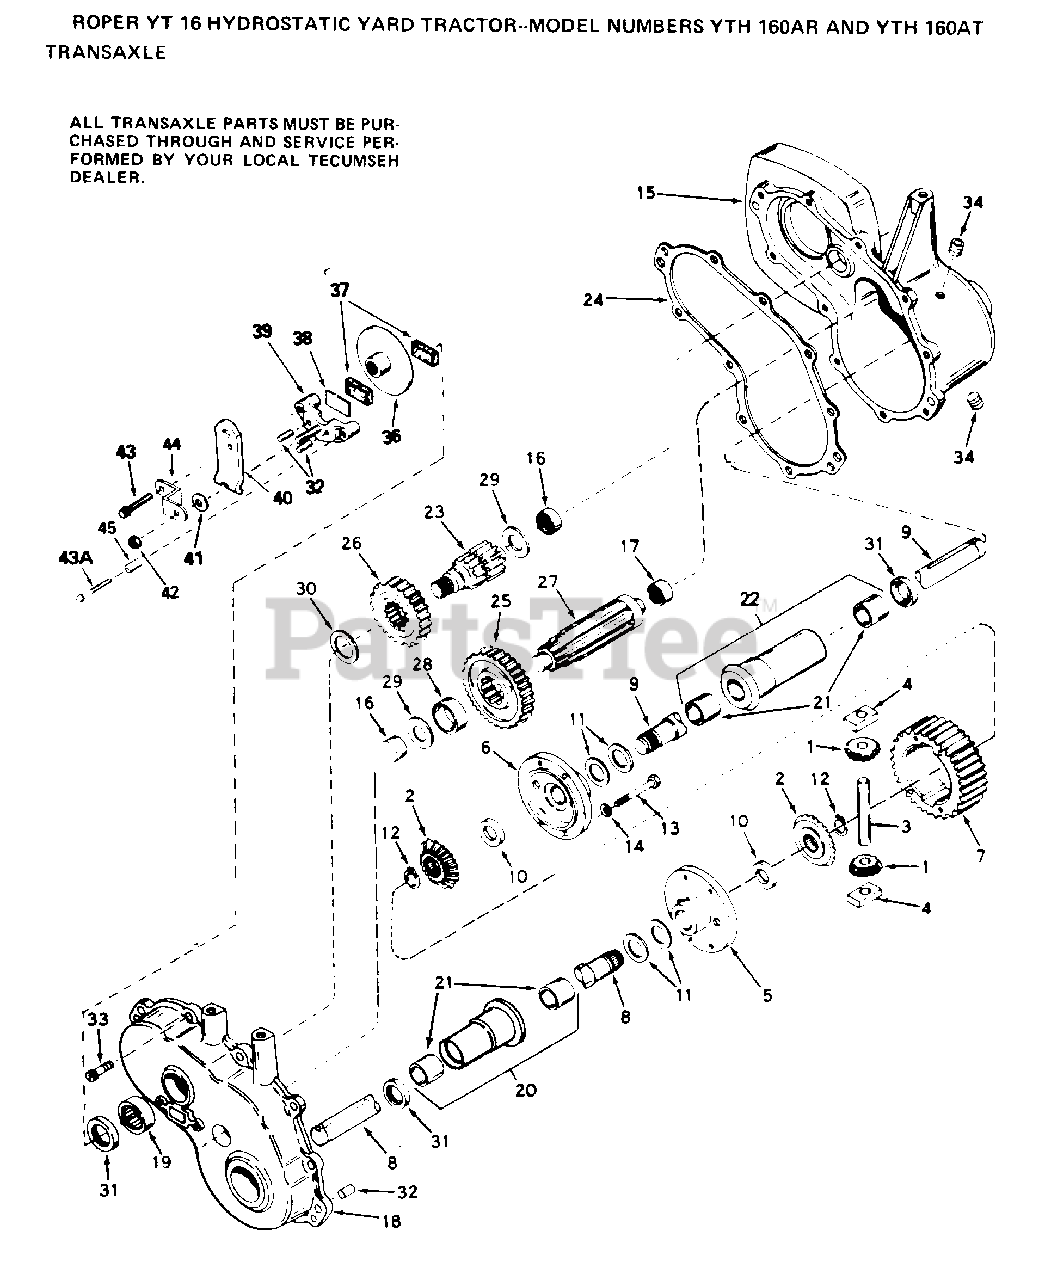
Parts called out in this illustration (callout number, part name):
1	PINION, 10T
4	BLOCK DRIVE
5	CARRIER, DIFFERENTIAL
6	CARRIER, DIFFERENTIAL
11	WASHER THRUST
13	SCREW, 1/4-20 X 2-1/4
14	WASHER LOCK 1/4
16	BEARING, NEEDLE
17	BEARING, NEEDLE
19	BEARING, NEEDLE
20	HOUSING & BUSHING ASSY
22	HOUSING & BUSHING ASSY
23	SHAFT, BRAKE
25	GEAR, OUTPUT
26	GEAR, IDLER
27	SHAFT, OUTPUT
30	WASHER, THRUST
36	DISK, BRAKE
38	PLATE BRAKE PAD
39	HOLDER BRAKE PAD
40	LEVER, BRAKE
41	WASHER, FLAT
42	LOCKNUT 5/16-24
43	SCREW, 1/4-20 X 1-1/4
43A	SCREW FLNG HEX 1/4-20 X 2-1/4
44	BRKT BRAKE LEVER
